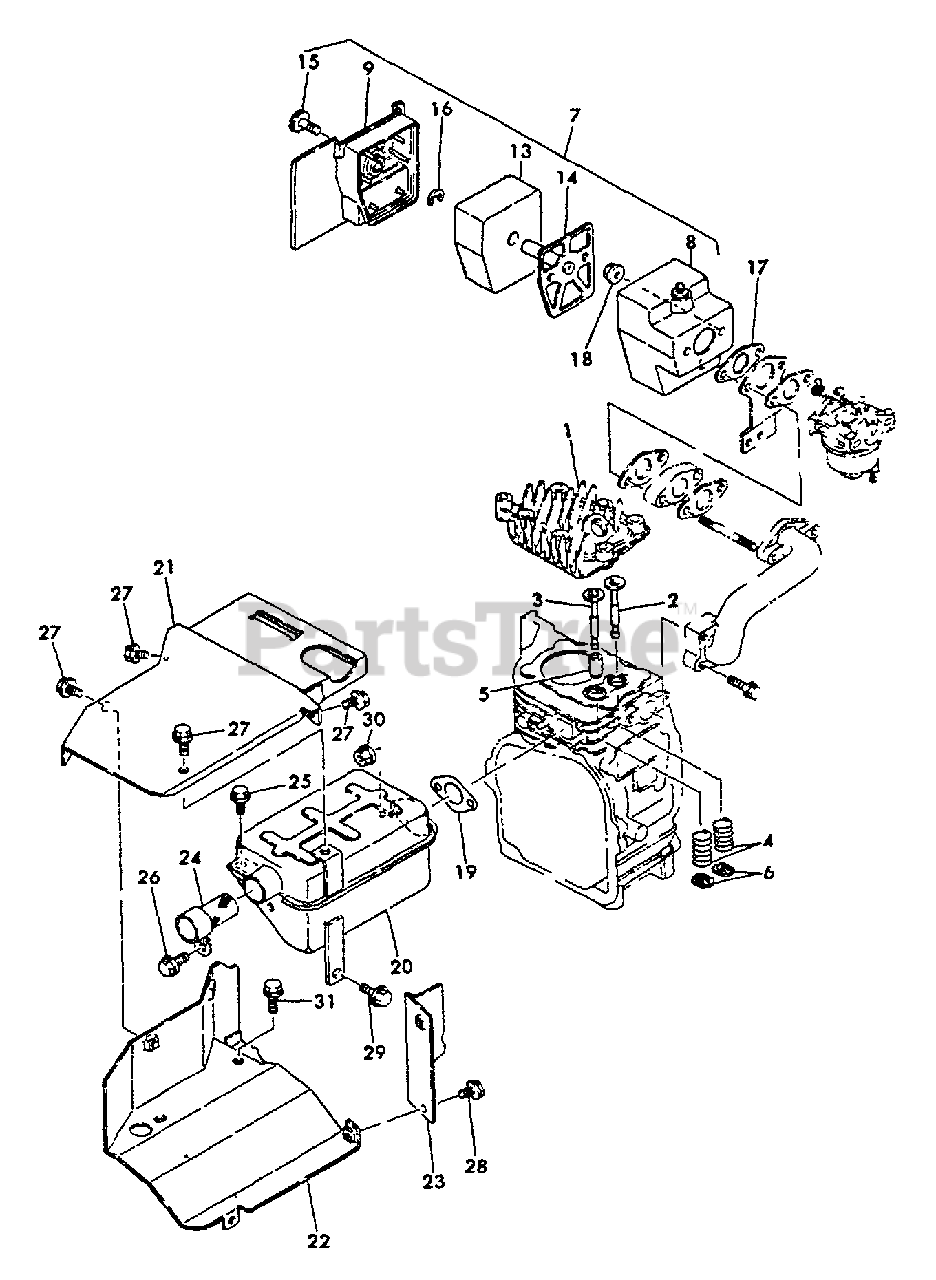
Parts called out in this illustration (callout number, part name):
1	HEAD, CYLINDER
2	INLET, VALVE
3	VALVE, EXHAUST
4	SPRING, VALVE
5	GUIDE, VALVE
6	RETAINER, VALVE
7	AIR CLEANER ASSY
8	CASE, AIR FILTER
9	COVER, AIR FILTER
13	FILTER, AIR
14	HOLDER, ELEMENT
16	RING, RETAINING - 5
17	GASKET, INTAKE
18	NUT - 6 -- FLANGE
19	GASKET, EXHAUST
20	MUFFLER
21	COOLING GUIDE (A)
22	COOLING GUIDE (B)
23	COOLING GUIDE (C)
24	ARRESTOR, SPARK
25	BOLT - 6X8 -- PLATED
26	BOLT - 6X8 -- PLATED
27	BOLT - 6X8 -- PLATED
28	BOLT - 6X8 -- PLATED
29	BOLT - 6X12 -- PLATED
30	NUT - 6 -- FLANGE
31	BOLT - 6X8 -- PLATED
